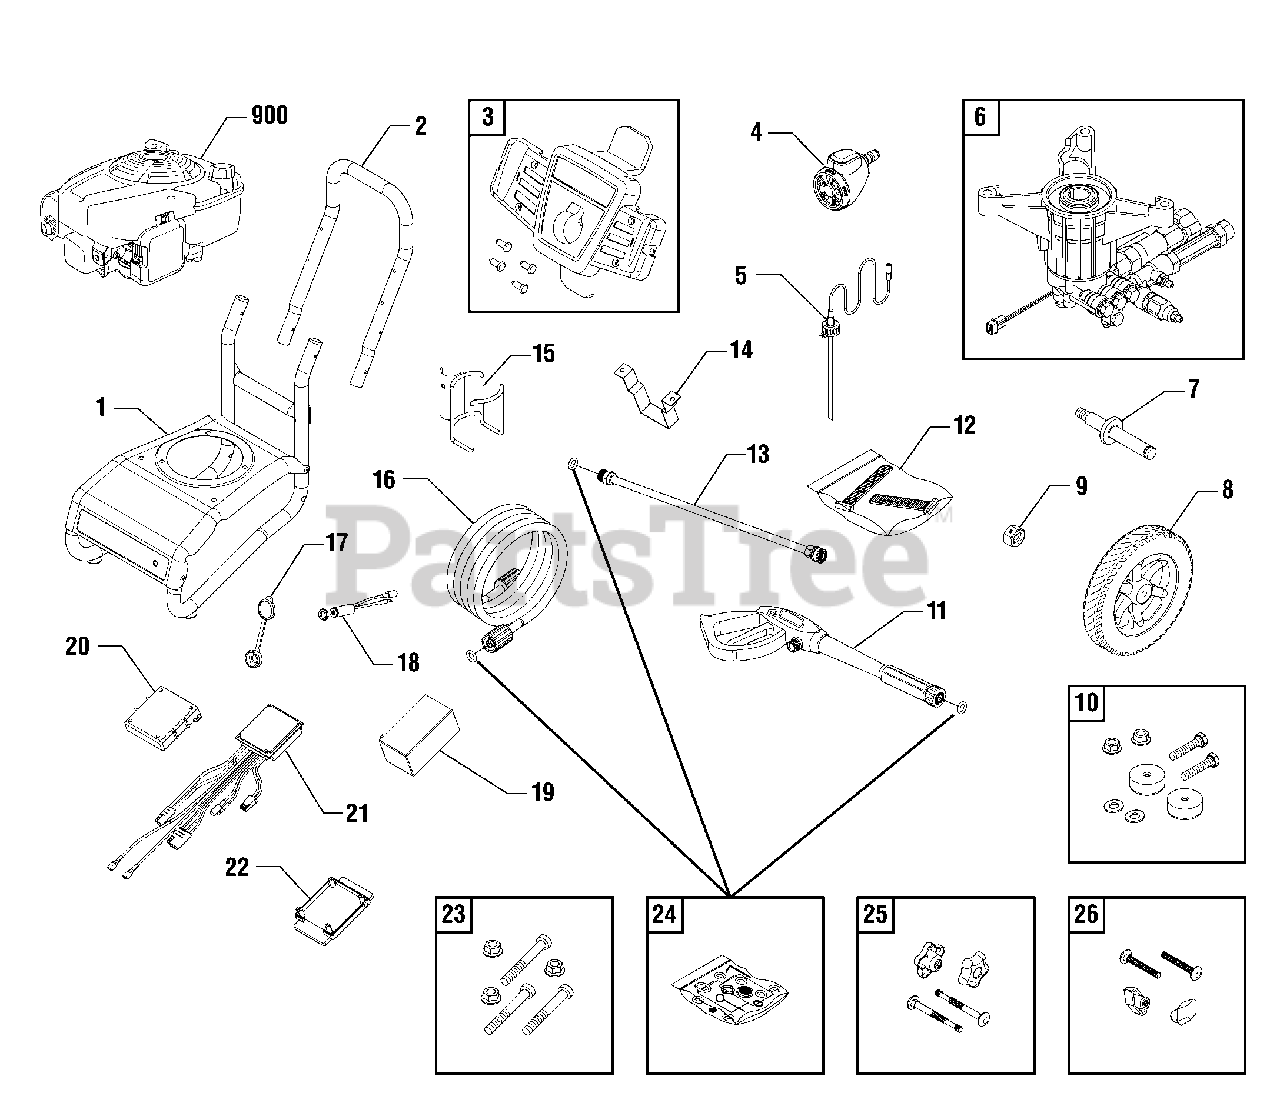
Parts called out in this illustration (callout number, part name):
10	MOUNT-VIBRATION
11	GUN
13	EXTENSION-QC
16	HOSE
19	BATTERY
21	CIRCUIT BOARD
23	KIT-HARDWARE PUMP MOUNTING
900	** ENGINE
